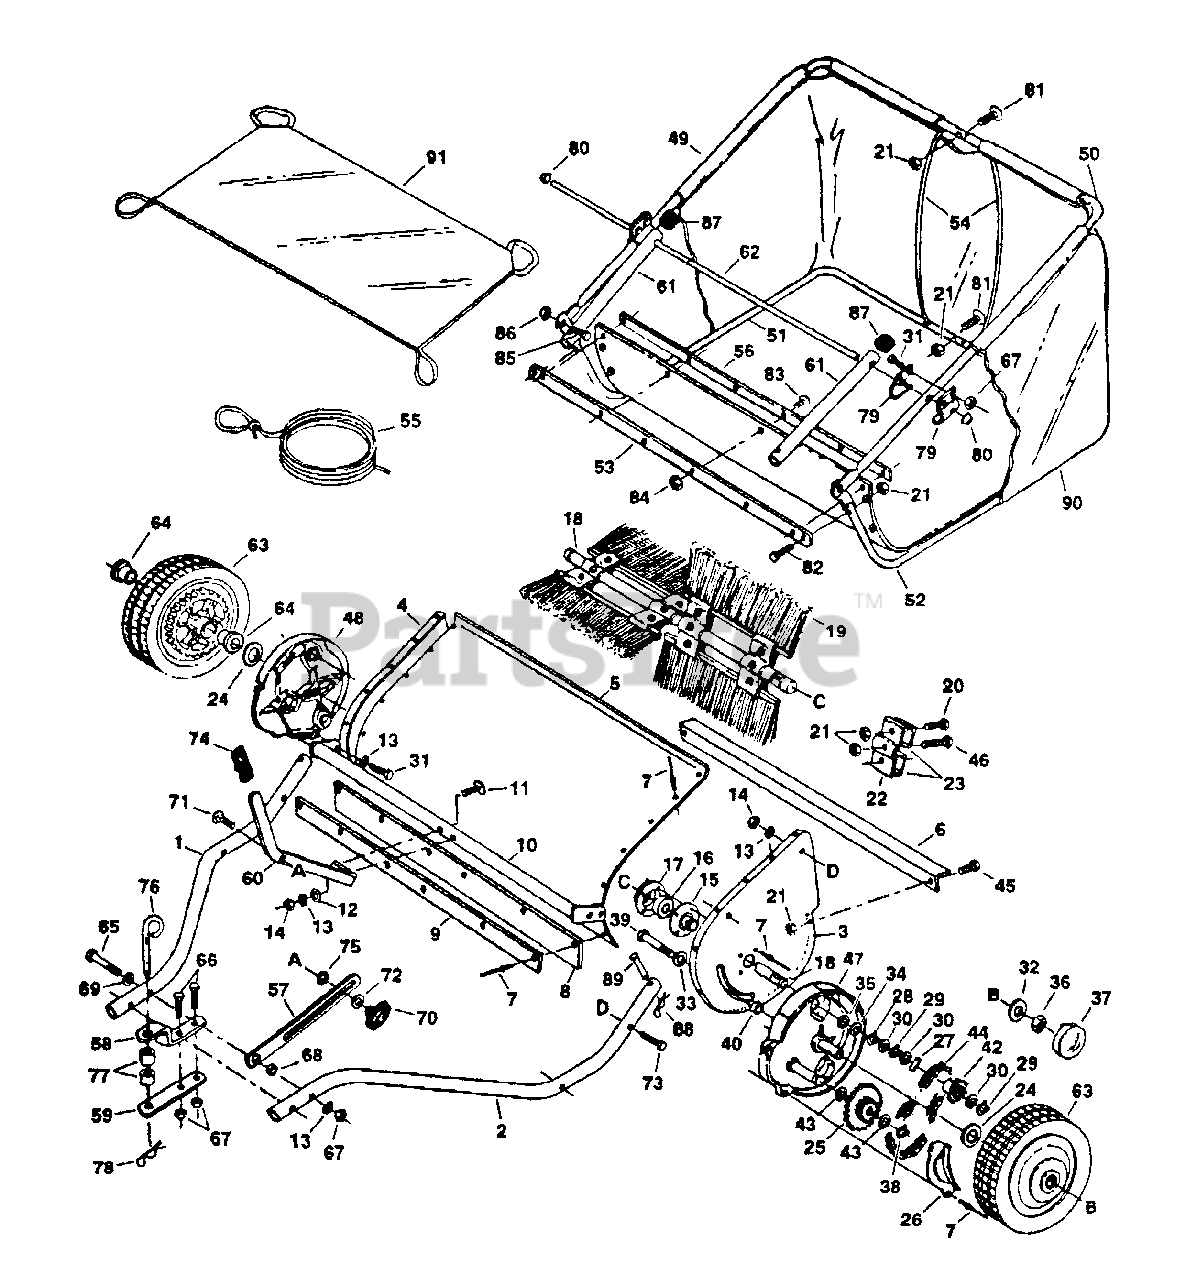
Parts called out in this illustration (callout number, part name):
1	Hitch Tube, R.H.
2	Hitch Tube, L.H.
3	End Plate, L.H.
4	End Plate, R.H,
5	Wrapper
6	Brace, Rear Support
7	Rivet, Pop
8	Skirt, 42"
9	Retainer, Skirt
10	Height Adjustment Tube Ass'y.
11	Bolt, Cvd. Hd 5/16-18 x 1-5/8" Lg.
12	Washer, Bowed 1" x .32" x .06"
13	Lock Washer, 5/16"
14	Nut, Hex 5/16-18 Thread
15	Brush Bushing Ass'y.
16	Ball Bearing
17	Retainer, Dust Cover
18	Brush Shaft
19	Brush, 42"
20	Bolt, Hex 1/4-20 x 3/4" Lg.
21	Nut, Hex Lock 1/4-20 Thread
22	Retainer, Brush (Double)
23	Retainer, Brush (Single)
24	Washer, Flat 1-1/8" x .78" x .025"
25	Sprocket / Gear
26	Dust Cover
28	Ring, Retaining 3/4"
29	Ring, Retaining .594"
30	Washer, Shim 1-1/8" X .594" x .025"
31	Bolt, Hex 5/16-18 x 3/4" Lg.
32	Washer, Flat 1-1/2" x .375" x .062"
33	Washer, 3/8" Std. Wrt.
34	Washer, Flat .78" x 1.25" x .06"
35	Washer, Flat .78" x 1.25" x .031"
36	Nut, Hex Lock 3/8-24 Thread
37	Hub Cap
38	Ring, Retaining 1/2"
39	Bolt, Hex 3/8-24 x 3-1/2" Lg.
40	Bushing, Spacer
42	Sprocket, Ratchet L.H.
43	Washer, 1/2" x 1" x .02"
44	Chain, Roller
45	Bolt, Hex 1/4-20 x 1/2" Lg.
46	Bolt, Hex 1/4-20 x 1" Lg.
47	Housing, Wheel Drive Ass'y. L.H.
48	Housing, Wheel Drive Ass'y. R.H.
49	Tube, Upper Hopper Frame R.H.
50	Tube, Upper Hopper Frame L.H.
51	Tube, Lower Hopper Frame R.H.
52	Tube, Lower Hopper Frame L.H.
53	Strap, Bag Frame
54	Rod, Hopper Support 34"
55	Hopper Rope
56	Retainer, Bag
57	Strap, Height Adjustment
58	Bracket, Hitch
59	Bracket, Hitch (Straight)
60	Handle, Height Adjustment
61	Tube, Bag Arm
62	Rod, Hopper Bag Pivot
63	Wheel & Tire Ass'y. (White)
63	Wheel & Tire Ass'y. (Yellow)
64	Wheel Bearing
65	Bolt, Hex 5/16-18 x 3" Lg.
66	Bolt, Hex 5/16-18 x 2-1/4" Lg.
67	Nut, Hex Lock 5/16-18 Thread
68	Bushing, Spacer
69	Washer, Flat (5/16) 11/32" x 11/16"
70	Knob, Wing 5/16-18 Thread
71	Belt, Carriage 5/16-18 x 3/4" Lg
72	Washer, Flat 5/16" Std. Wrt.
73	Bolt, Hex 5/16-18 x 1-3/4" Lg.
74	Grip, Height Adjust
75	Washer, Tooth Lock 5/16"
76	Pin, Hitch
77	Tube, Hitch Spacer
78	Hairpin Cotter, 1/8" #4
79	Clamp, Hopper Mount
80	Palnut, 3/8"
81	Bolt, Cvd. Hd. 1/4-20 x 1" Lg,
82	Bolt, Hex 1/4-20 x 1-1/4" Lg.
83	Bolt, Sl. Tr. Hd. #10-32 x 5/8" Lg.
84	Nut, Hex Lock #10-32 SEMS
85	Bolt, Hex 3/8-16 x 3/4" Lg.
86	Nut, Hex Lock 3/8-16 Thread
87	Cap, Vinyl
88	Hairpin Cotter, 3/32" #3
89	Pin, Clevis 1/4" x 1-1/2" Lg.
90	Hopper Bag
91	Wind Screen
